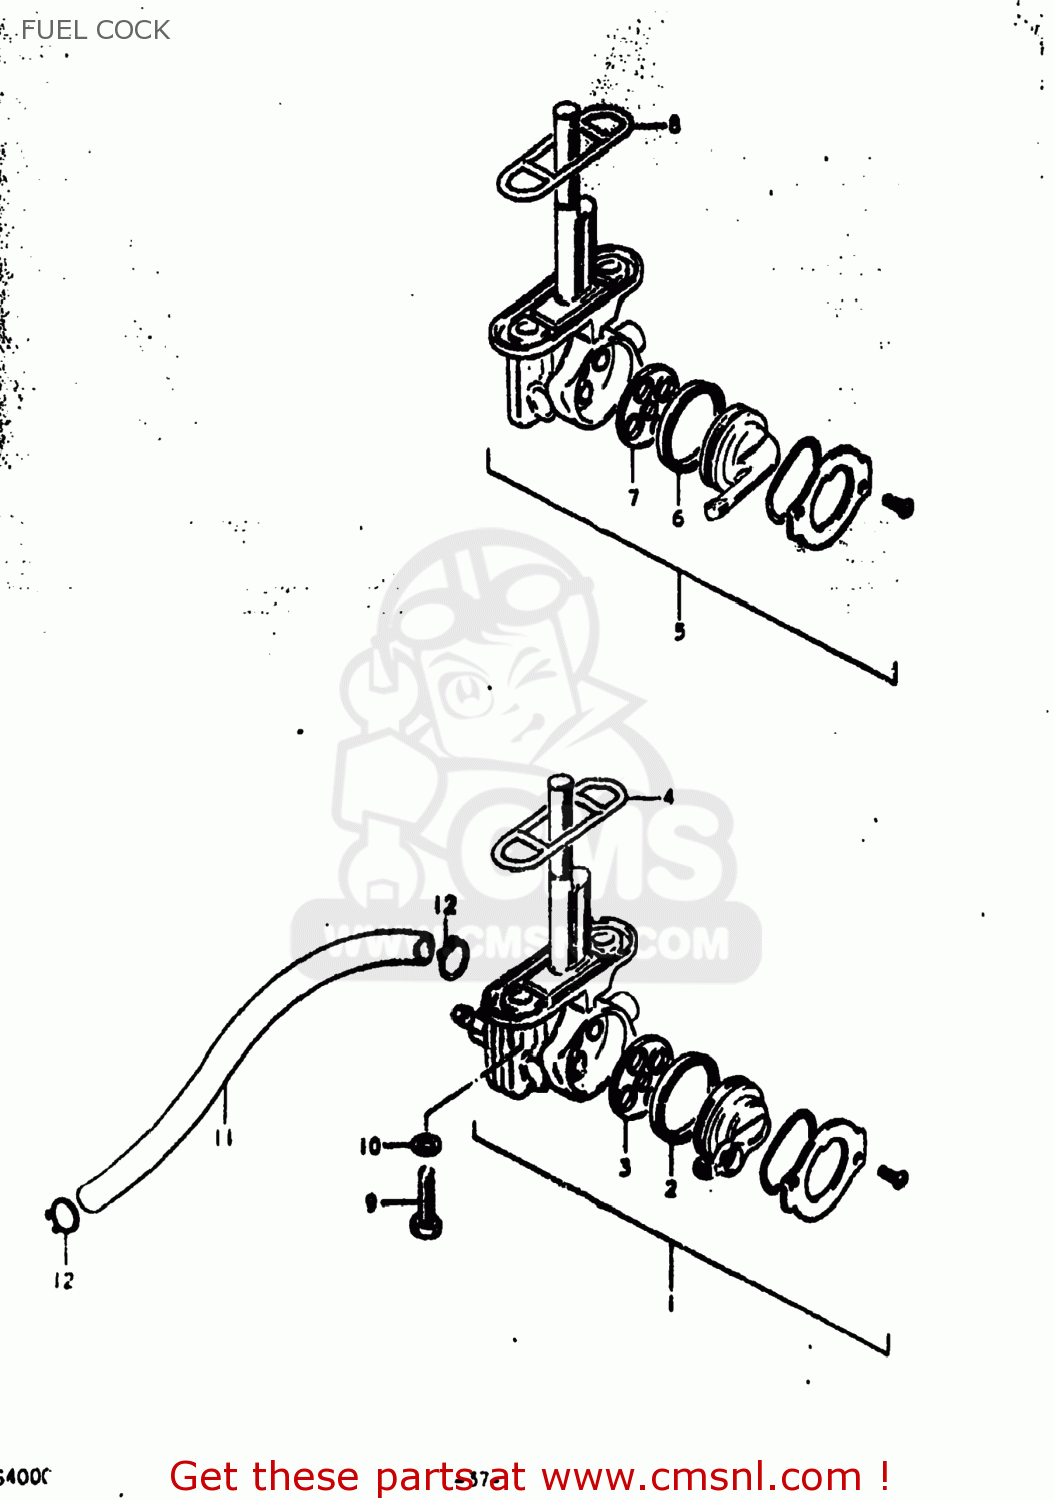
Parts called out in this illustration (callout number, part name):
1	COCK ASSEMBLY,FUEL
2	V SEAL,FUEL COCK
3	GASKET (NAS)
4	GASKET,FUEL COCK (NAS)
5	COCK ASSEMBLY,FUEL
6	V SEAL,FUEL COCK
7	GASKET (NAS)
8	GASKET,FUEL COCK (NAS)
9	BOLT(6X20)
10	GASKET
11	HOSE
12	CLIP
